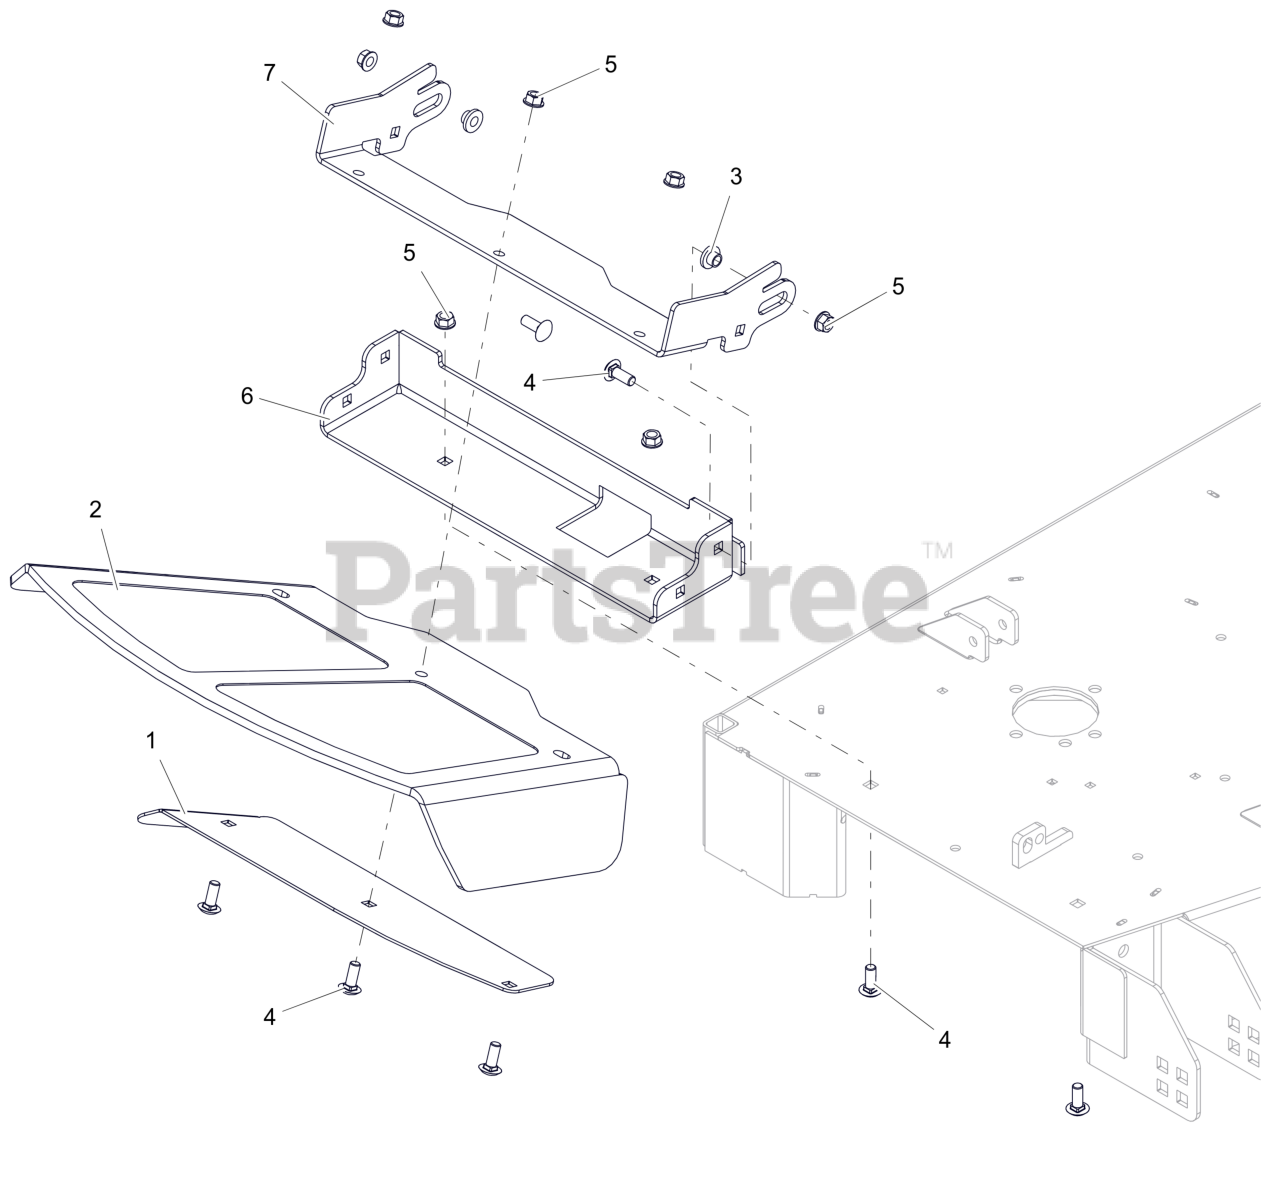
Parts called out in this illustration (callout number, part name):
1	48-60 DISCH CHUTE CLMP PLT-RED
2	CHUTE, FORMED RUBBER DISCHARGE
3	BSHG-FLG .385X.500X.875X.406
4	BLT,RHSSN .38-16X1.00 G5 ZCC
5	NUT-LK-CTR-FLG .375-16 GF ZCC
6	BASE, 48" DISCHARGE CHUTE MTG BRKT (RED)
7	BRKT- CHUTE MTG
